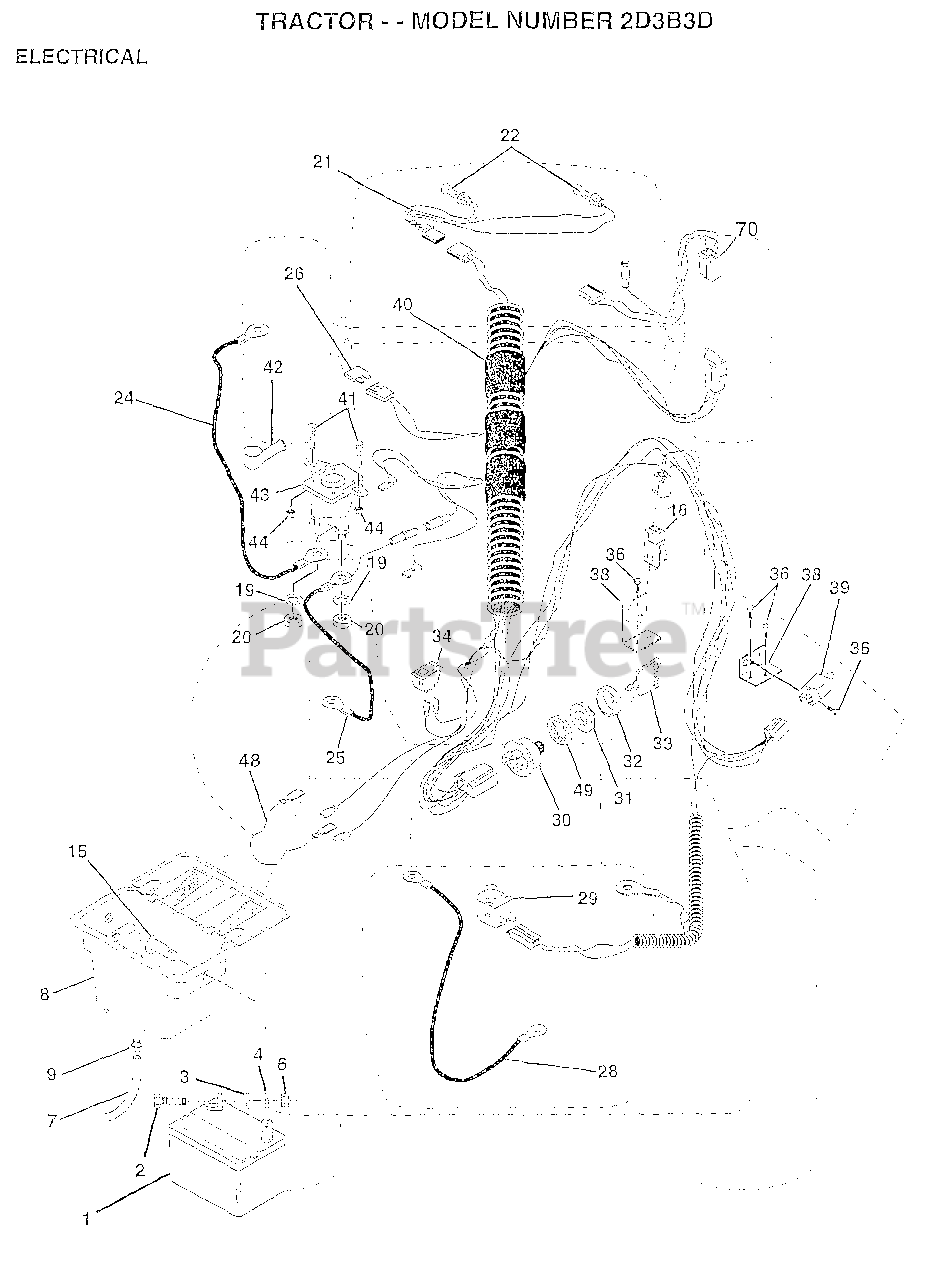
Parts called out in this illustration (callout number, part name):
3	WASHER
4	LOCKWASHER
7	TUBE T
9	HOSE CLAMP T
15	FASTNER.SNAP-IN
16	SWITCH INTERLOCK
20	NUT
21	"HARNESS,LIGHT SOC"
22	HEADLAMP BULB
24	"CABLE T, BATTERY"
25	CABLE.BTRY.6GA.RD
26	FUSE HYT
28	CABLE T
29	SWITCH SEAT
32	COVER KEY SWITCH
33	KEY MLD GEN DELTA
34	SWITCH LT
36	SCREW
38	BRACKET SWITCH IN
39	SWITCH INTERLOCKT
40	HARNESS.IGN.DASH.
41	BOLT HXHD FIN
44	NUT HXKEP 1/4X20
48	ADAPTER AMMETER
49	WASHER PINNED
70	HARNESS ENG DUAL
